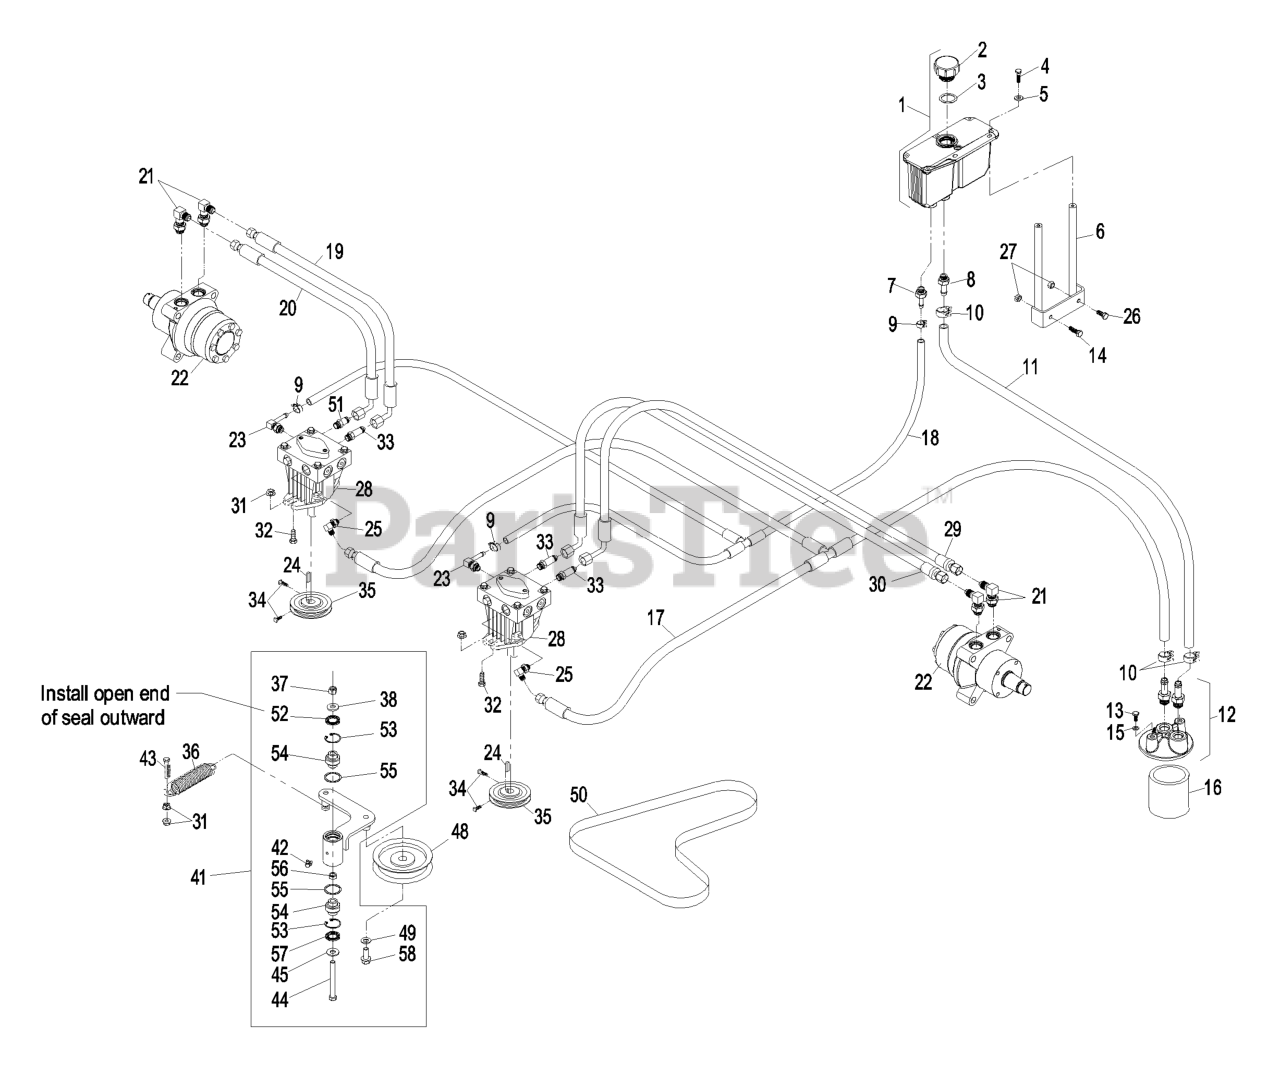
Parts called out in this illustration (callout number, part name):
1	HYD RESERVOIR ASM
2	Cap-Reservoir, HYD
3	GASKET-CAP
4	SCREW-HH
5	WASHER-FLAT
6	STAND-RESERVOIR
7	ADAPTER-STRAIGHT
8	ADAPTER-STRAIGHT
9	CLAMP-HOSE
10	CLAMP-HOSE
11	HYD HOSE ASM
12	FILTER HEAD ASM
13	SCREW-HH
14	SCREW-HH
15	WASHER-LOCK
17	HYD HOSE ASM
18	HYD HOSE ASM
19	HOSE,HYDRAULIC
20	HOSE 10.00" HIGH PRES.
21	HOSE,HYDRAULIC
22	MOTOR-WHEEL
23	ELBOW-90 DEG
25	FITTING-ELBOW, 90 DEG
26	SCREW-HH
28	PUMP-HYD
29	HOSE-REAR, LH
31	NUT-HHF, WHIZ
32	SCREW-HH
33	ADAPTER-STR, LONG
34	SCREW-SET
36	SPRING-EXTENSION
37	NUT-LOCK, NI
38	WASHER-BELLEVILLE
39	SCREW-HHF
40	SEAL-LIP, DOUBLE
42	FITTING-GREASE, 90 DEG
43	SCREW-HH
44	SCREW-HH
45	WASHER-FLAT
49	WASHER-FLAT
50	BELT-COG
51	ADAPTER-STRAIGHT
52	SEAL-LIP, SINGLE
53	RING-SNAP
54	BEARING-SPHERICAL
